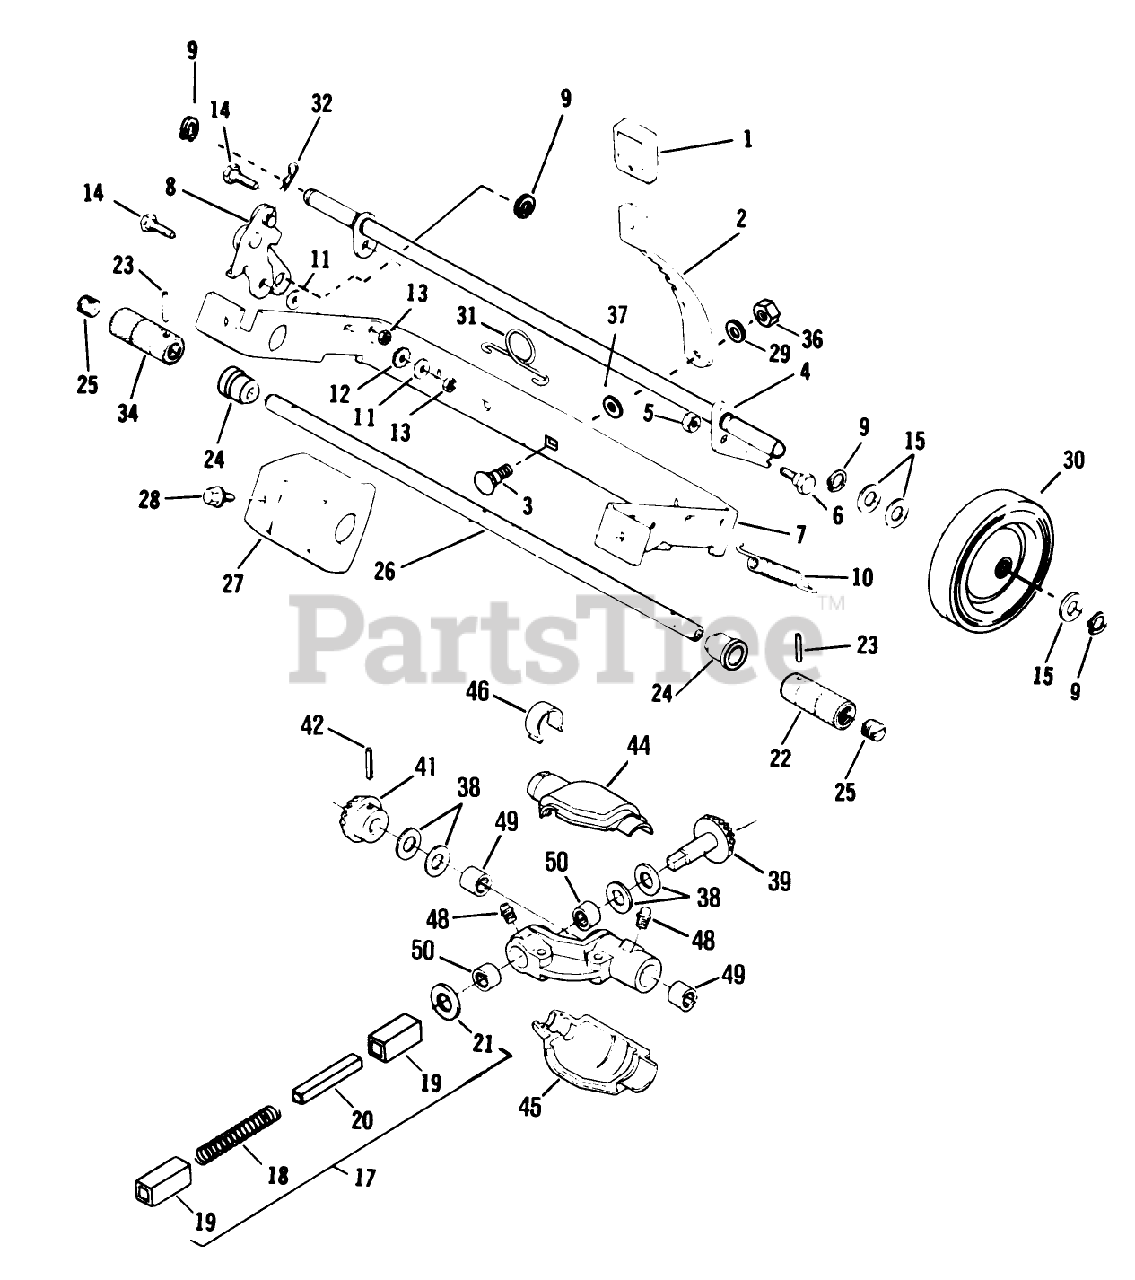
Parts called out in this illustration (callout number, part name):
1	KNOB
2	LEVER
4	AXLE & TORQUE LUG ASM
5	LOCKNUT E
6	BOLT RB&W
7	BRACKET *GREEN
9	RET RING
10	SPRING
11	WASHER S
13	STOP NUT
14	BOLT RB&W
15	SPACER
18	SPRING
19	BUSHING BKWY
21	THRUST WASHER
22	ROLLER-LEFT
23	PIN
24	SLEEVE &BEARING AY
25	GREASE PLUG
26	DRIVE SHFT TAG AY
29	WASHER S
31	SPRING N.A.S
33	RET RING
36	LOCKNUT E
37	WASHER SPRING LAR
38	THRUST WASHER
39	GEAR BEST
41	GEAR ADVANCE
42	ROLL PIN
44	GEAR COVER UPPER
48	**FITTING LINCOLN
